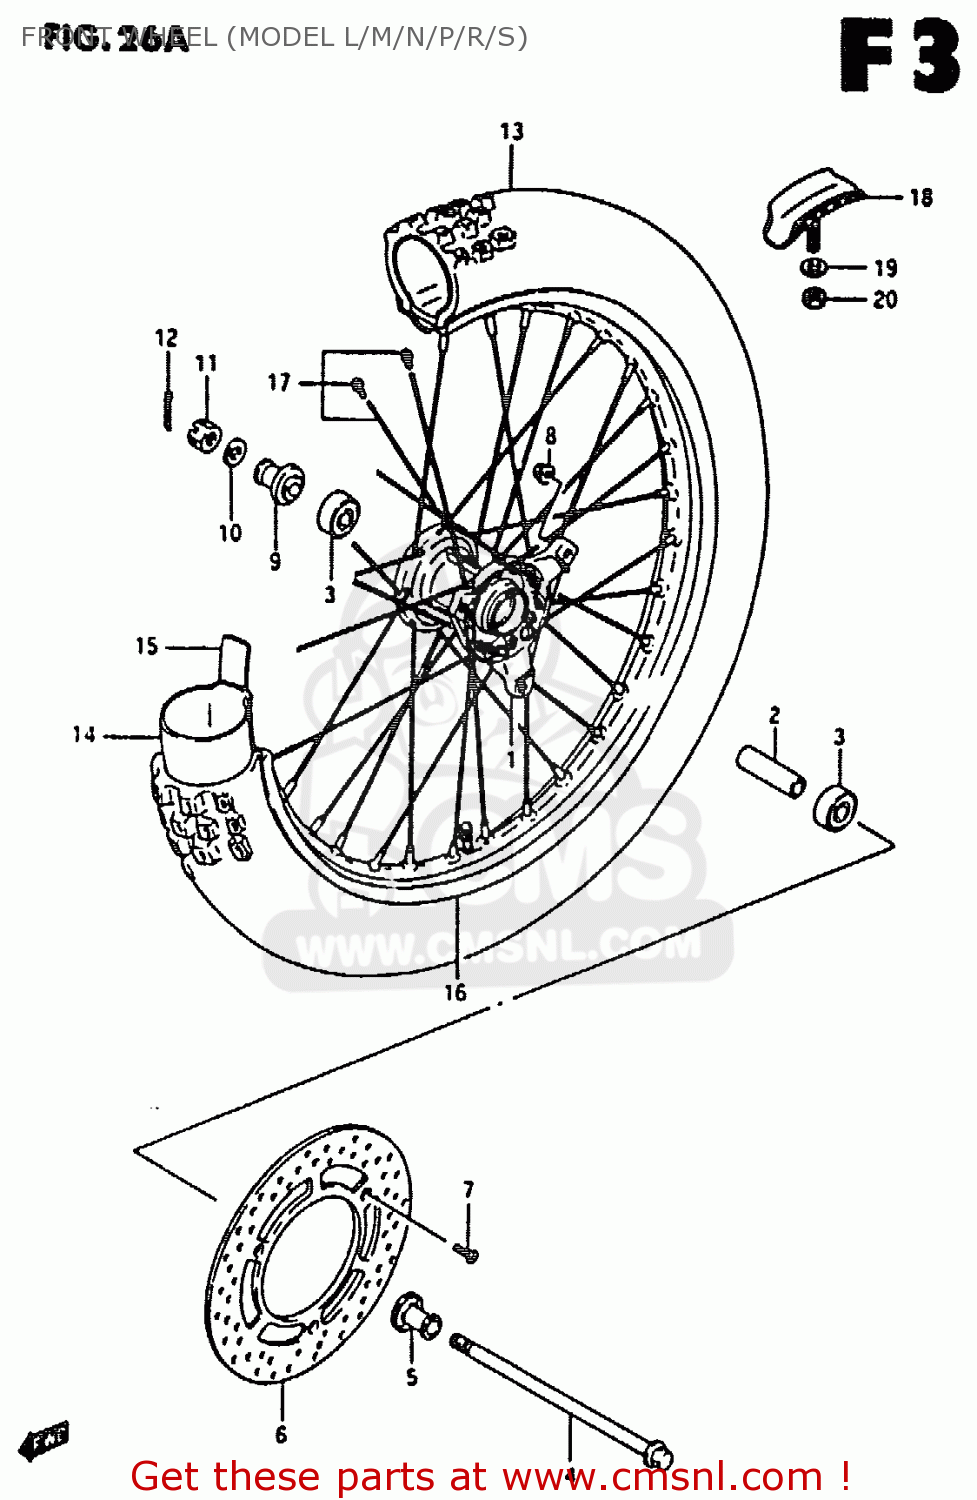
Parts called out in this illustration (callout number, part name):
1	HUB,FR WHEEL
2	SPACER,FR HUB BEARING
3	BEARING (12X32X10)
4	AXLE,FR
5	SPACER,FR AXLE
6	DISC,FRONT BRAKE
7	SCREW(6X22)
8	NUT
9	WASHER
10	NUT, REAR AXLE
11	PIN 20X20
12	TIRE,FRONT
13	TUBE,INNER
14	PROTECTOR,WHL INR TUBE
15	RIM,FR WHEEL(1.40X17)
16	SPOKE SET,FR WHEEL
17	STOPPER,BEAD
18	WASHER
19	NUT
20	NUT
